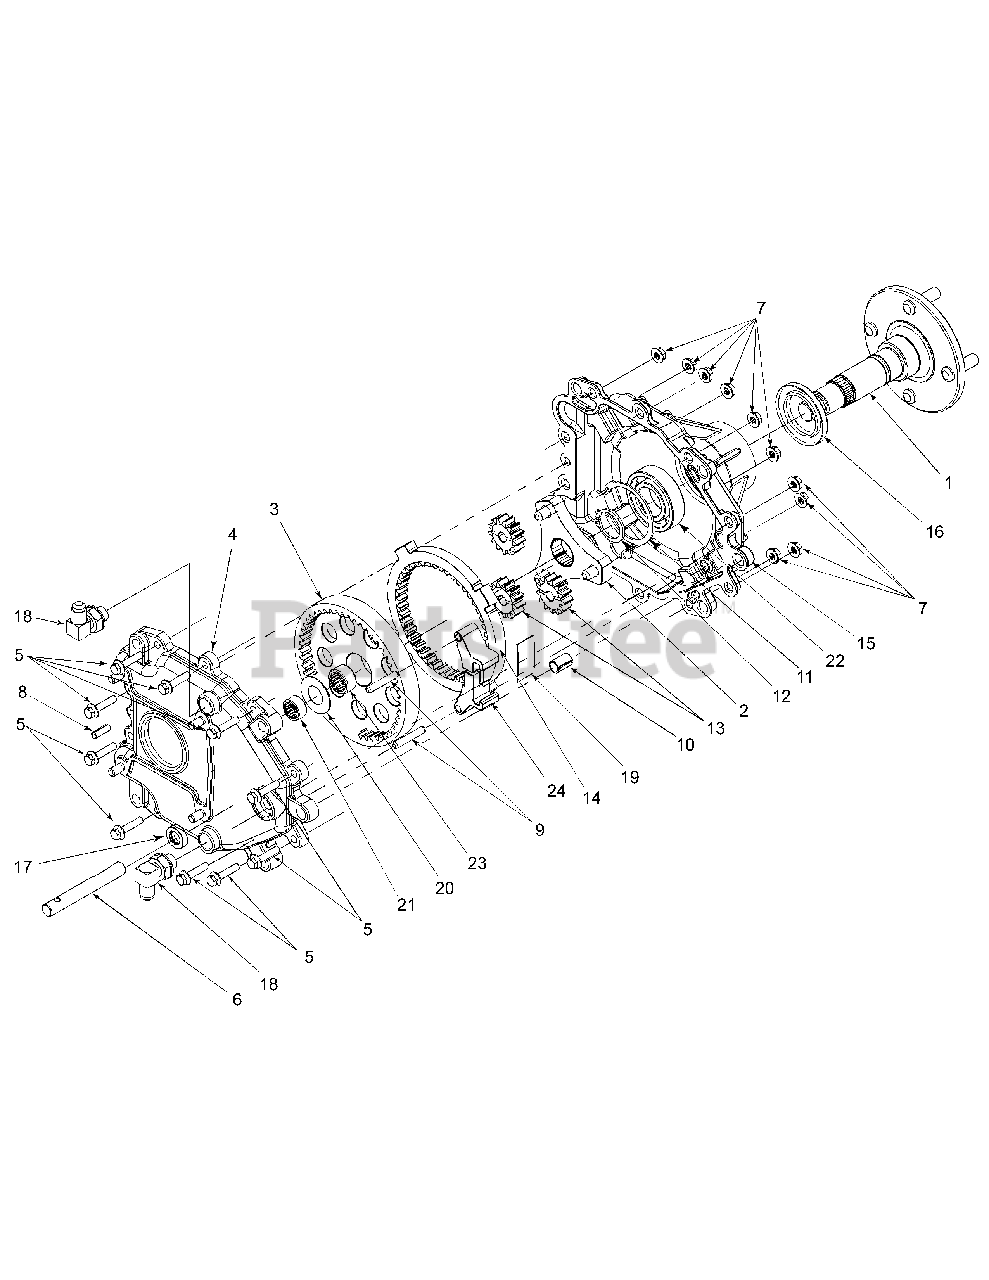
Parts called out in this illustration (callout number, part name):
1	Axle Assembly
1	Ribbed Neck Stud
2	Carrier Assembly, Output
3	Gear Assembly, 51T Internal & 20T
4	Housing Ass’y
5	Hex Washer Screw 1/4-20 x 1-1/8
7	Hex Flange Lock Nut 1/4-20
10	Bushing
11	Inverted Retaining Ring
13	Spur Gear 13T
14	Ring Gear 46T
15	Axle Outer Housing
16	Oil Seal
18	Elbow Fitting
19	Brake Shoe Spring
20	Shim Washer .76 x 1.5 x .030
20	Shim Washer .76 x 1.5 x .010
20	Shim Washer .76 x 1.5 x .020
21	Needle Bearing
22	Ball Bearing
23	Needle Bearing
